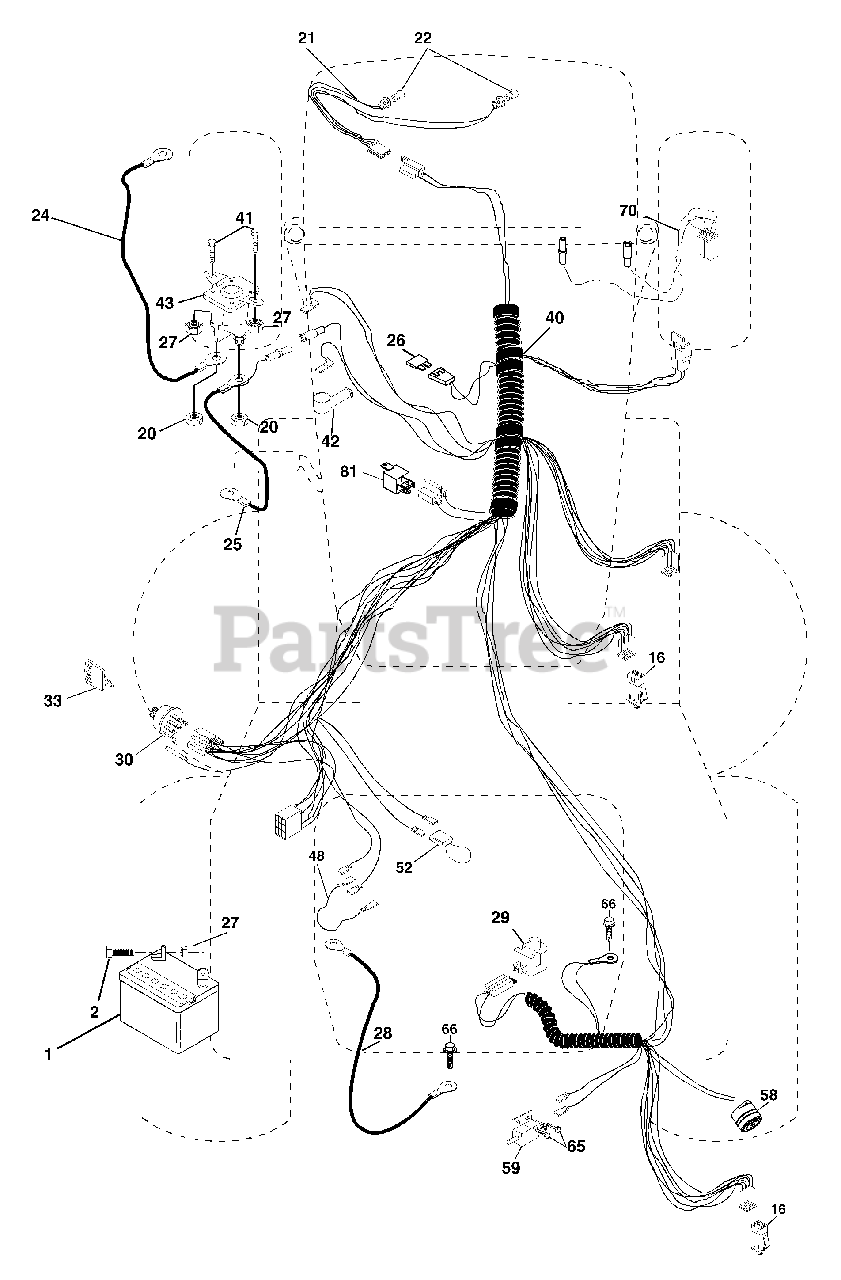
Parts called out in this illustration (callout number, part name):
1	Battery 12 Volt 25 AMP Wet
2	Bolt Hex Hd 1/4-20 Unc X 3/4
16	Switch Interlock Push-In
20	Nut Jam Hex 1/4-20 Unc
21	Harness Asm Light W/4152J
22	Bulb Light #1156
24	Cable Starter 6Ga 11" Red
25	Cable Battery Crd 56" Red
26	Fuse 15 Amp
27	Nut Keps Hex 1/4-20 Unc
28	Cable Ground 6Ga 18" Black
29	Switch Plunger Normal Op Olive
30	Switch Ignition
33	Key Ign Molded
40	Harness Ign Crd Noram
41	Bolt Flk Fin Hex 1/4-20 Unc X 1/2
42	Cover Terminal Red
43	Solenoid
48	Adapter Ammeter Rectangular
52	Protection Wire Loop
58	Buzzer Crd
59	Switch FBI CRD
65	Screw Slftp #10-16 x 1/2 Ty-Ab
66	Screw Thdrol 3/8-16 x 1/2 Ty-Tt
70	Harness Engine B&S
